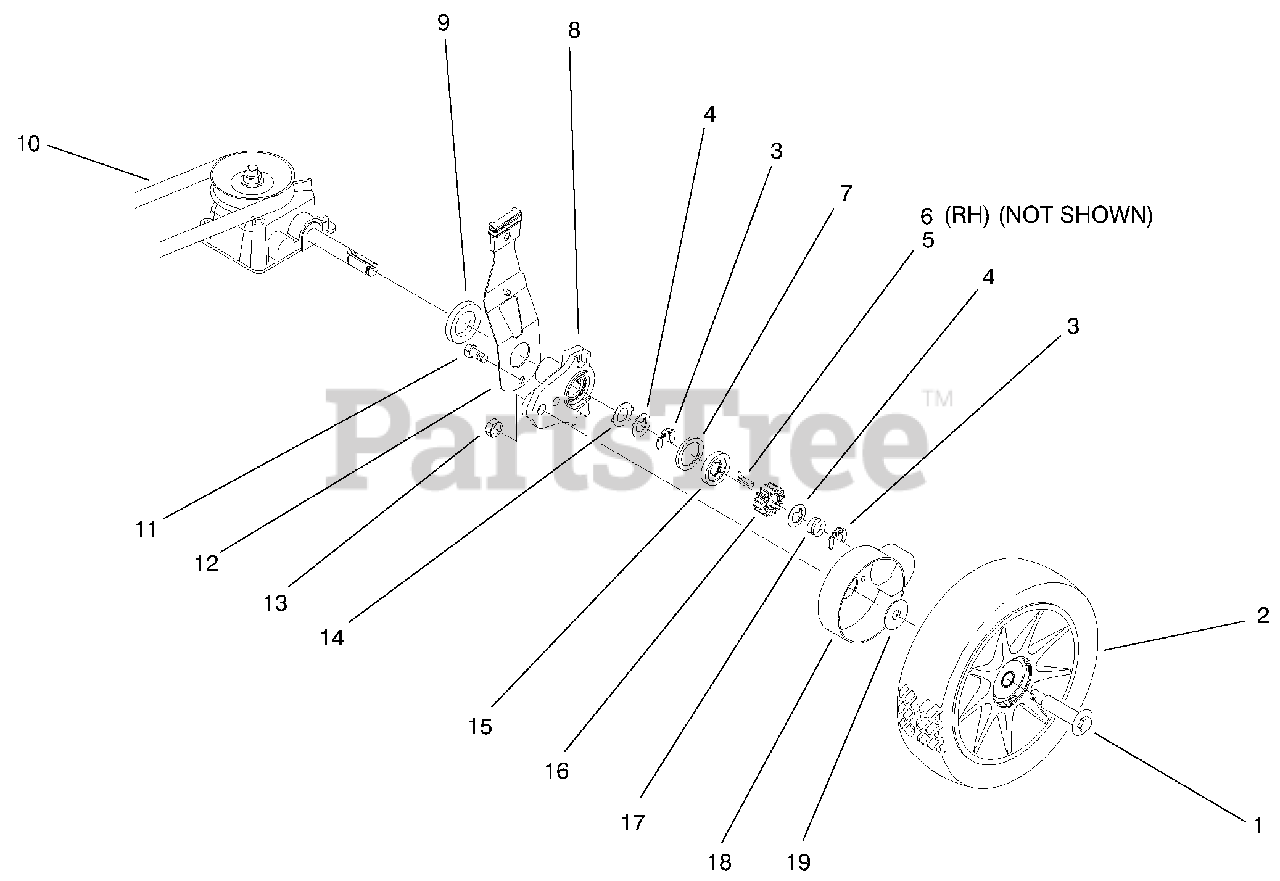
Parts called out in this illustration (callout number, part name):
1	Bolt-Shoulder
3	Ring-Retaining
4	Washer-Thrust
5	Key-Rocking
6	Key-Rocking
7	Ring-Friction
8	ASM-Hgt Adj Arm
9	Spacer-Axle Shaft
12	ASM-Spring Arm
13	Nut-Lock
14	Washer-Thrust
16	Gear-Pinion
17	Spring-Compression
18	Cover-Wheel
19	Washer-Stepped
